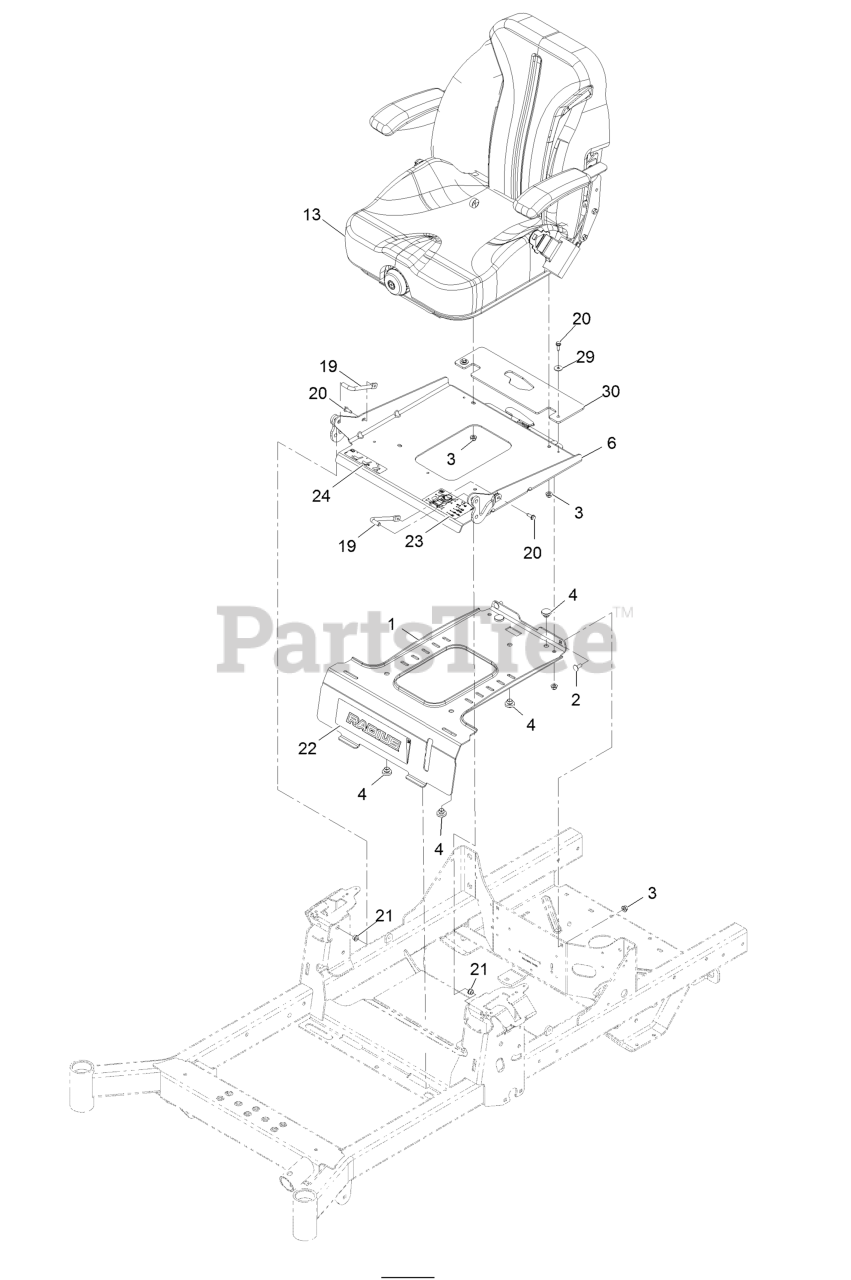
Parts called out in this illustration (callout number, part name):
1	Plate-Retainer, Tank
2	Bolt-Carriage 5/16-18 X 3/4 Short Neck
3	Nut-Nyloc 5/16-18 Flg
4	Bumper, Seat
6	Seat PAN And Latch ASM
13	ASM-Susp Seat
19	Pin-Pivot, Seat
20	Screw-HWH 1/4-20 X 3/4
21	Bushing-Flanged
22	Decal-Radius Logo
23	Decal-Aid, Service
24	Decal-Latch, Seat
29	Washer-Flat
30	Guard-Seat, Rubber
